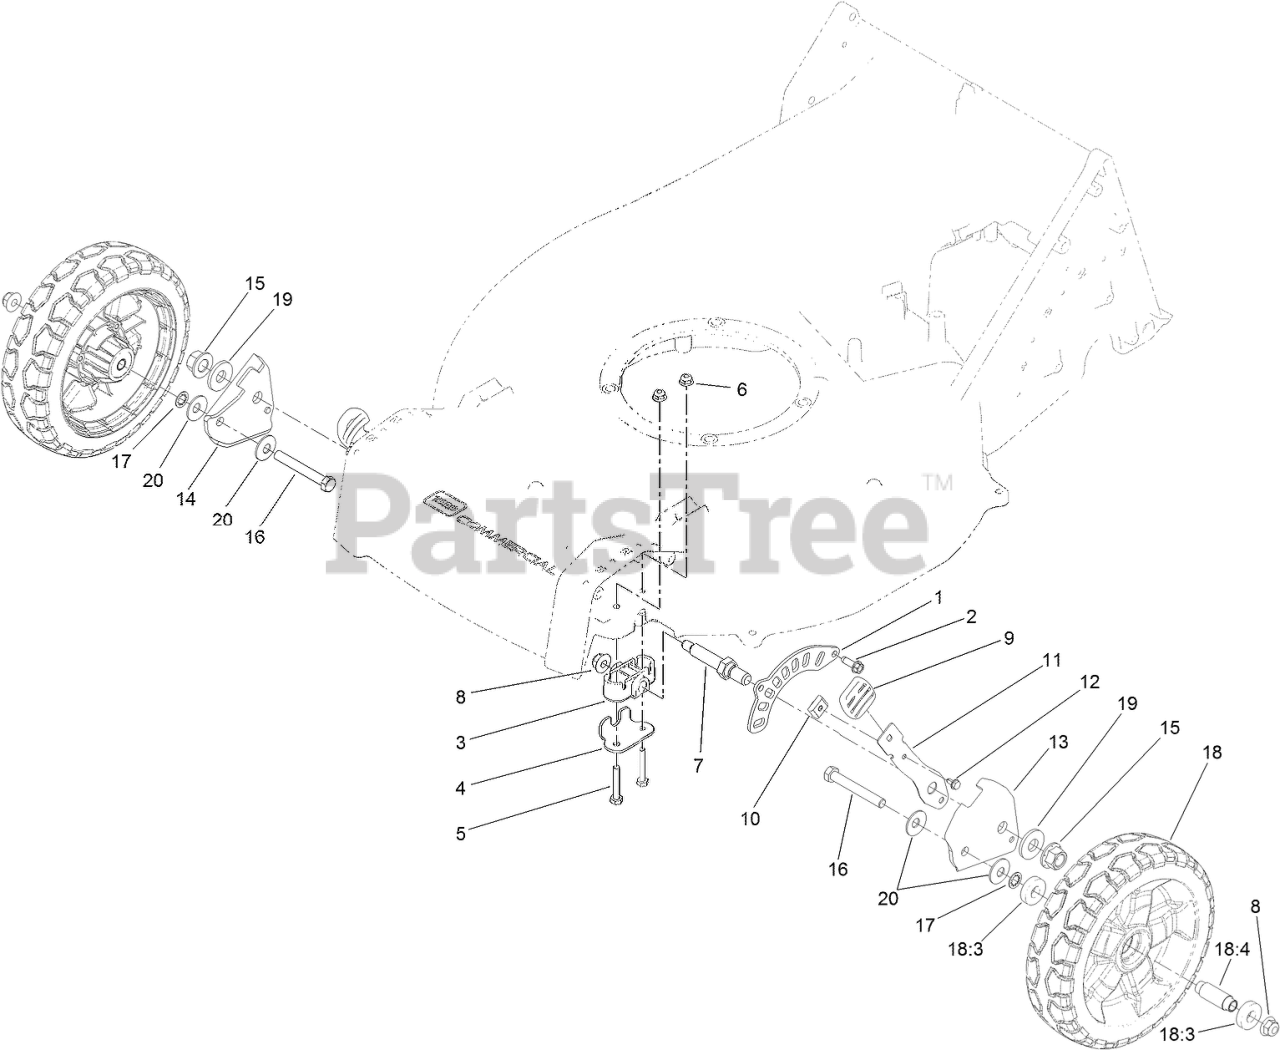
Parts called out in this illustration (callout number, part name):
1	PLATE-HOC, FRONT
2	SCREW-HWHTF
3	BUSHING-AXLE, FRONT HOC
4	RETAINER-BUSHING, FRONT AXLE
5	SCREW-HH
6	NUT-HF
7	AXLE-WHEEL
8	NUT-HF, NI
9	KNOB-LEVER, HOC
10	KEY-ARM, SPRING
11	ARM-SPRING
12	SCREW-HWH
13	ARM-PIVOT, FRONT LH
14	ARM-PIVOT, FRONT RH
15	NUT-LOCK
16	SCREW-HH
17	WASHER-LOCK, INTERNAL
18	WHEEL
18:3	BEARING-WHEEL
18:4	SPACER
19	WASHER-SPRING
20	WASHER-SPRING
